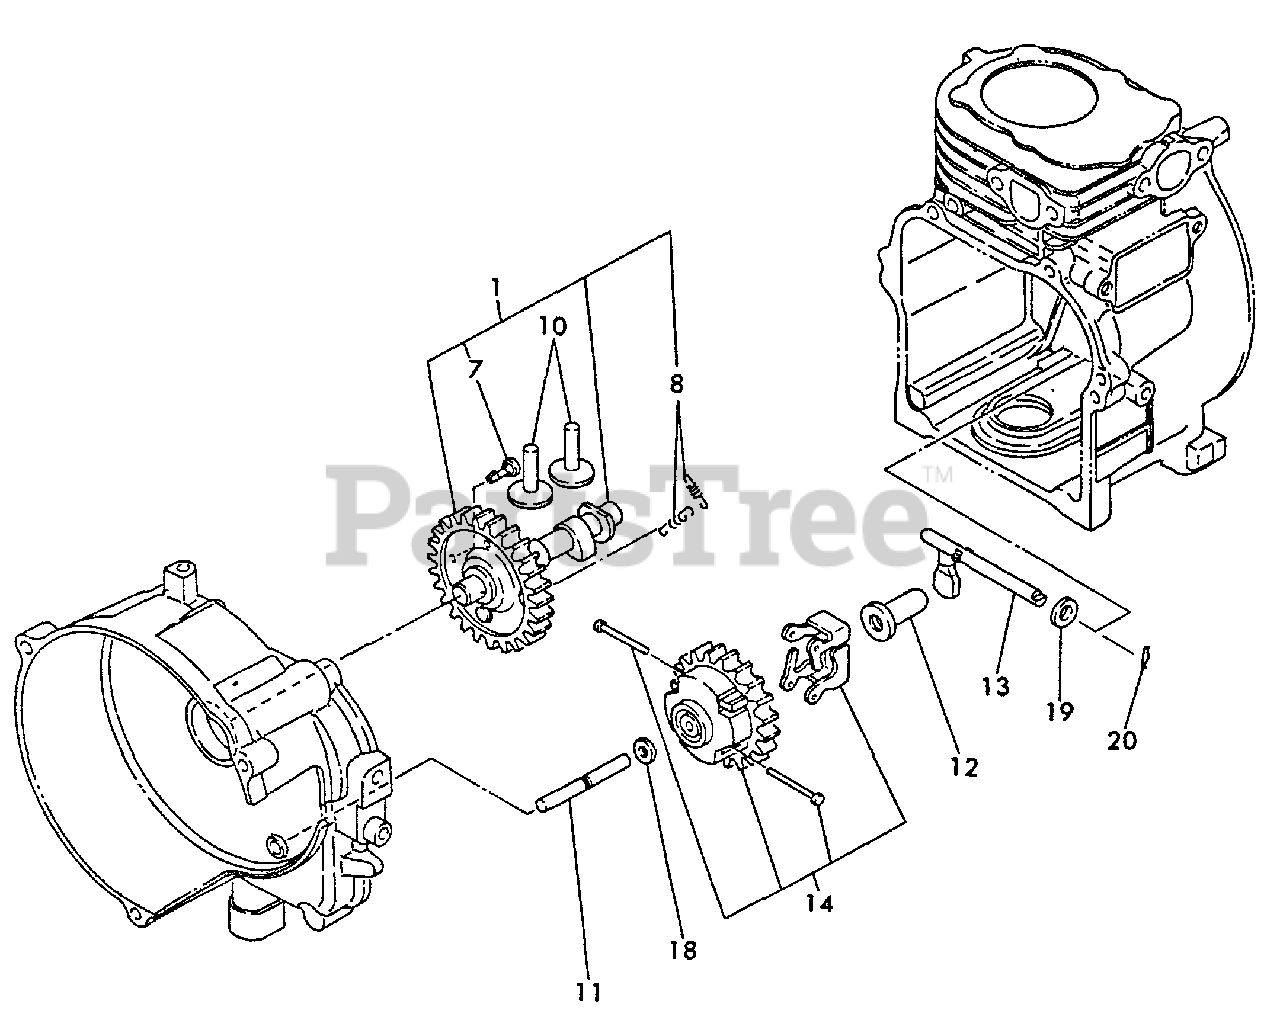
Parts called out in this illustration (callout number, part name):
1	CAMSHAFT ASSY
7	PIN
8	SPRING
10	TAPPET
11	SHAFT, GOVERNOR
12	SPINDLE, GOVERNOR
13	SHAFT, GOVERNOR LEVER
14	GOVERNOR GEAR ASSY
18	WASHER
19	WASHER - 6
20	PIN - 6 -- SNAP
